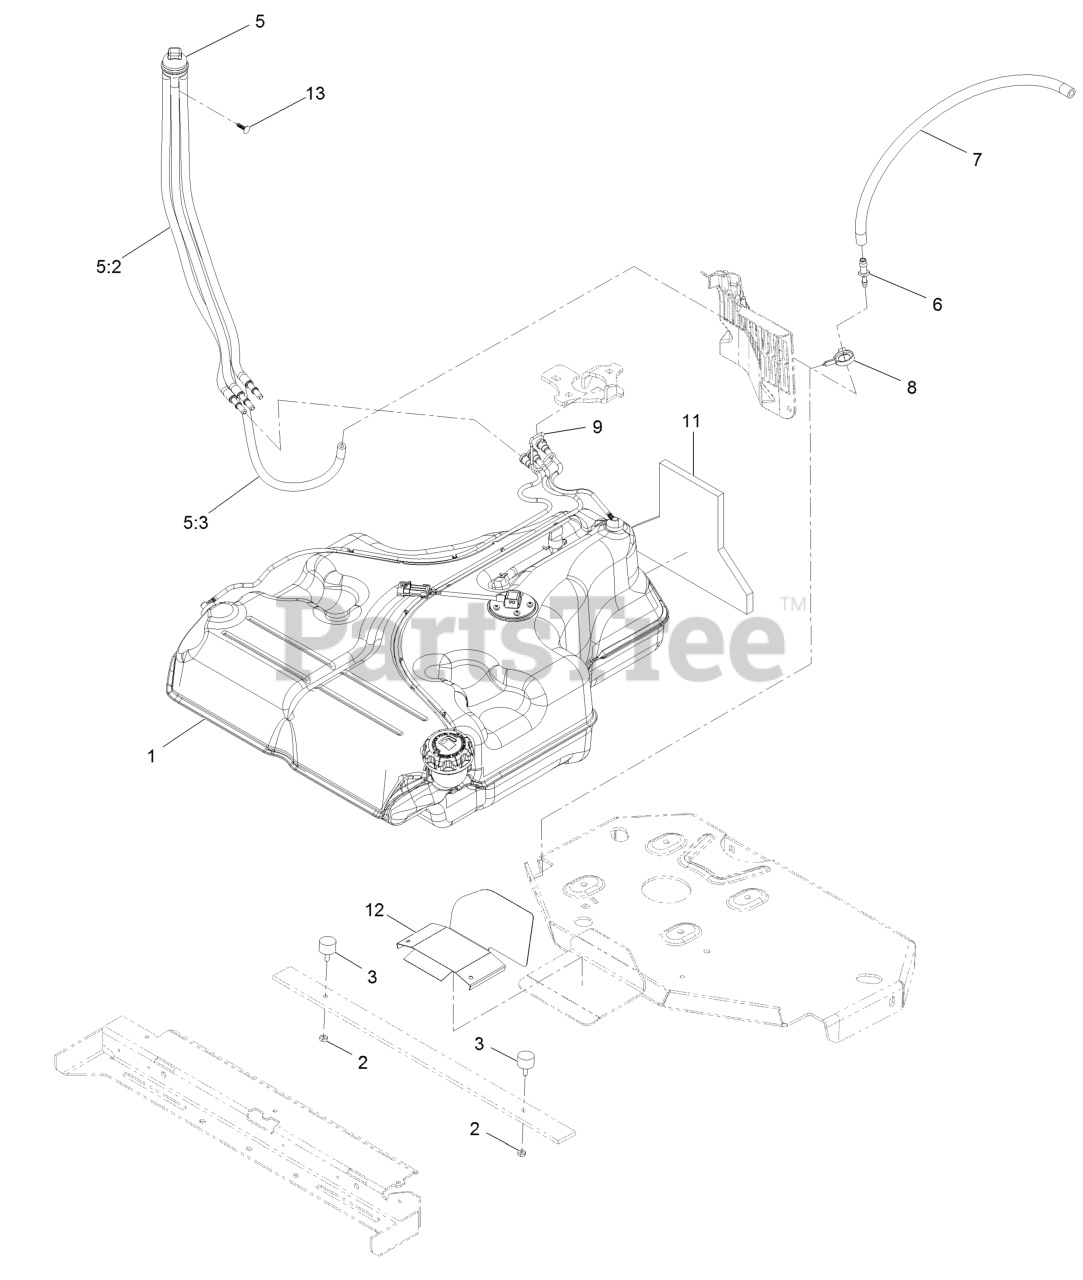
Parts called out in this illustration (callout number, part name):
1	Fuel Tank ASM
2	Nut-Jam 1/4-20
5	Fuel Manifold Vent ASM
5:2	Hose-Fuel Line 24"
5:3	Hose-Fuel
6	Fitting-Straight
7	Hose-Fuel
8	Clamp-Hose
9	Retainer-Line, Vapor
11	Insulation-Fuel Tank Foam
12	Guard-Exhaust
13	Plug-Plastic
